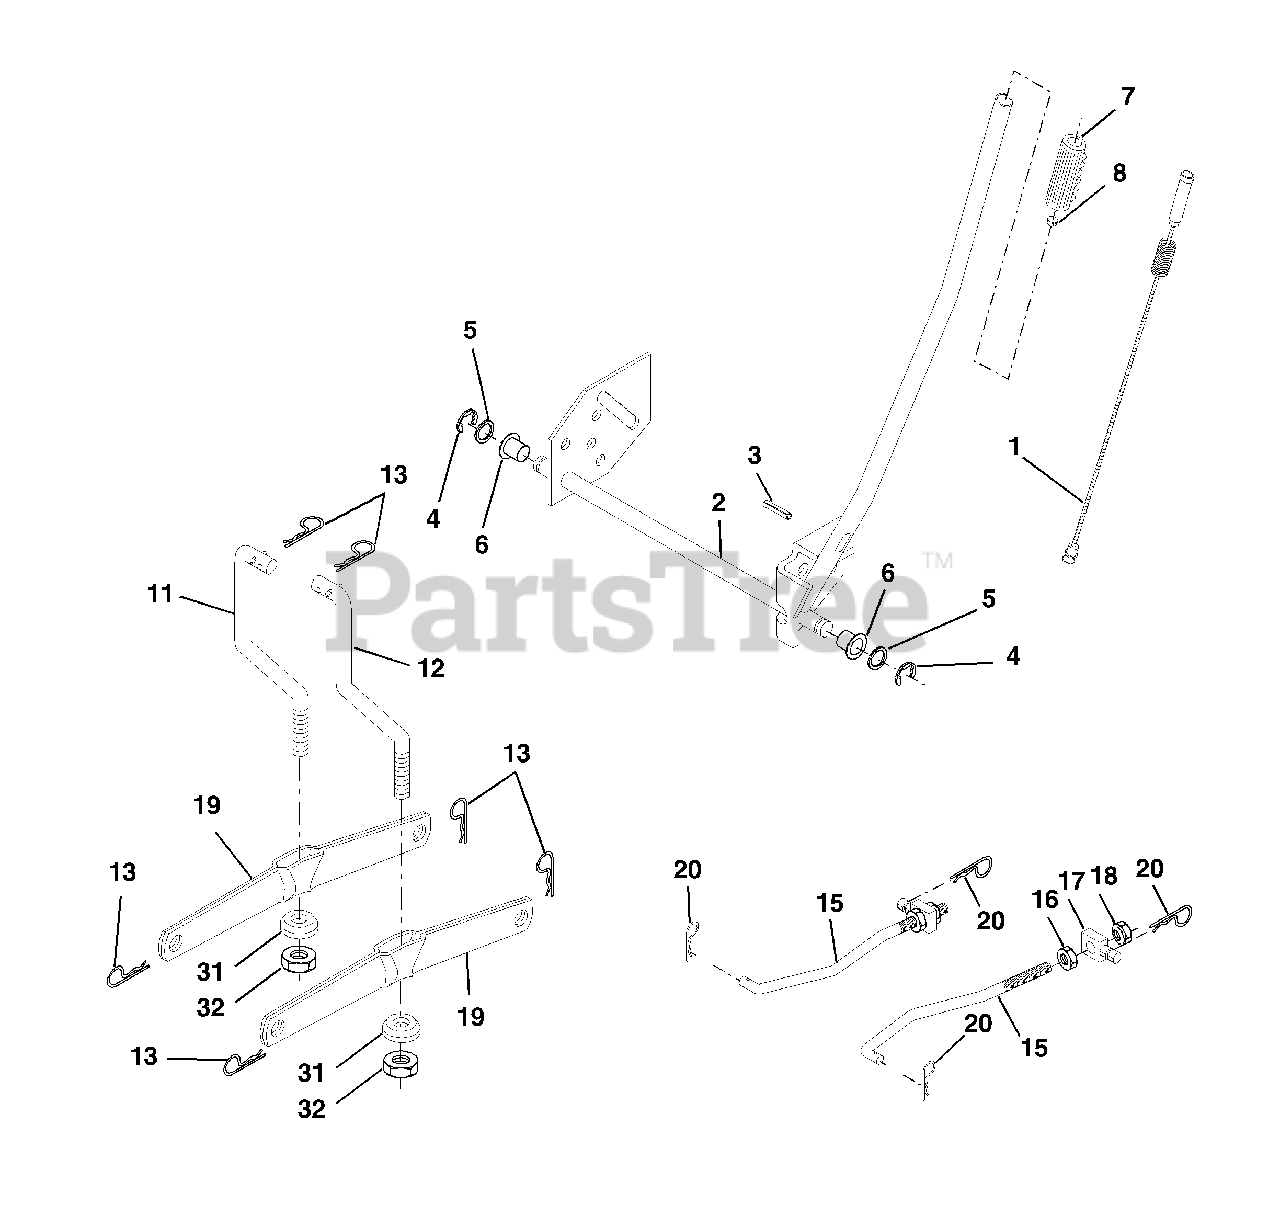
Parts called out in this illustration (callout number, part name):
1	Wire Asm Inner/Sprg w/plunger
2	Shaft Asm Lift RH
3	Pin Groove 1 500 Zinc
4	E Ring #5133-62
5	Washer 21/32 X 1 X 21 Ga
6	Bearing Nylon Blk 629 Id
7	Grip Handle Bicycle Matte Blk
8	Button Plunger Black
11	Link Lift LH Fixed Length
12	Link Lift RH Fixed Length
13	Retainer Spring
15	Link Front
16	Nut Jam Hex 1/2-13 Unc
17	Trunnion Blk Zinc
18	Nut Lockw/Wsh 1/2-13 Unc
19	Arm Suspension Rear
20	Retainer, Spring
31	Bearing Pvt Lift Spherical
32	Nut Crownlock 3/8-24
